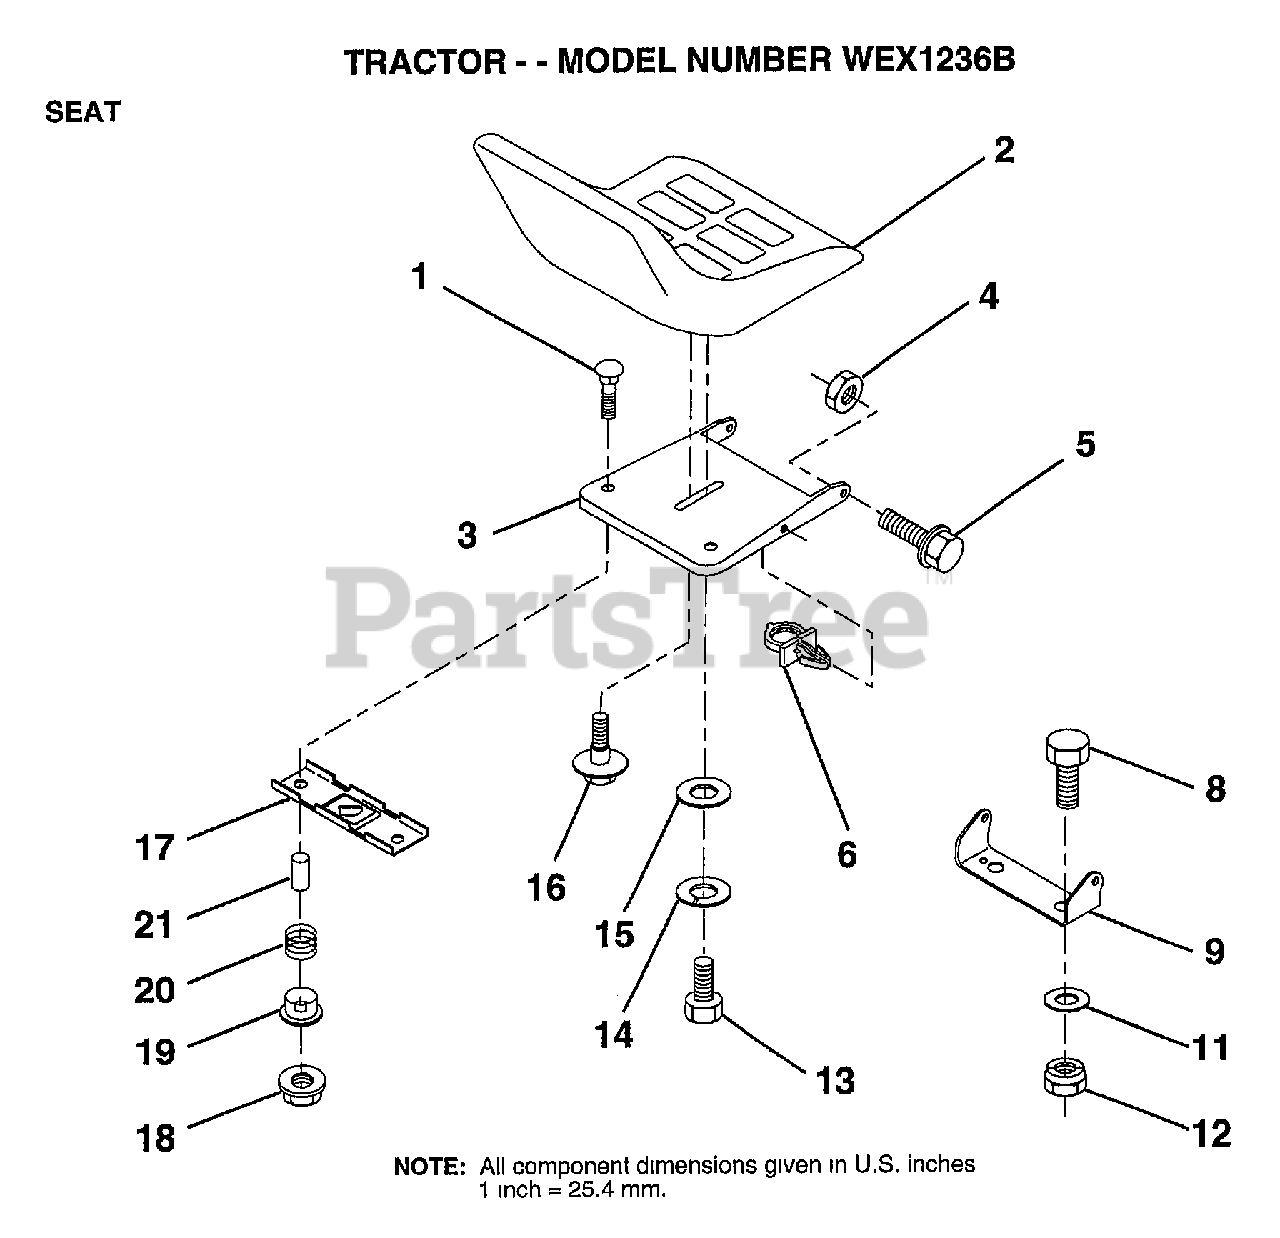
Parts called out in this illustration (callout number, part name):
1	BOLT-RD HD SQ NK
3	PAN-SEAT
4	NUT
5	"BOLT,SHOULDER"
6	CLIP.PUSH-IN.HING
8	BOLT
9	BRACKET PVT SEAT
11	WASHER
12	NUT
13	BOLT
14	LOCKWASHER
15	WASHER
16	"BOLT,SHOULDER"
17	BRKT SWITCH
19	BUSHING
20	SPRING
21	SPLIT SPACER
